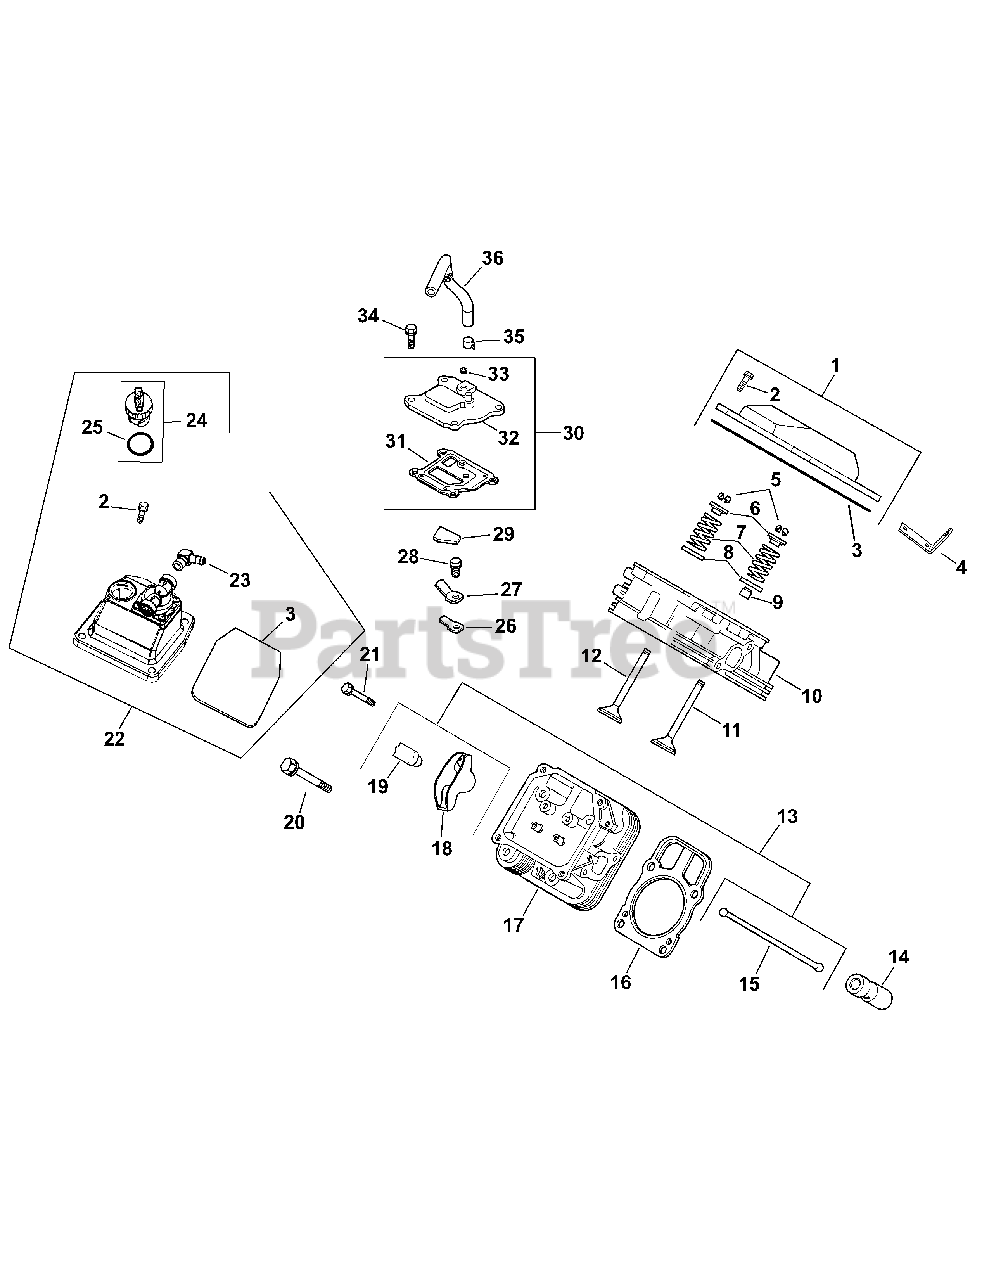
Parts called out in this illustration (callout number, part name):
1	Kit, Valve Cover-Plain Inc. 2, 3)
2	Screw, Flg M6x1.0x30
3	O-Ring, Valve Cover
4	Strap, Lifting
5	Kit, Retainer
6	Cap, Valve Spring
7	Spring, Valve
8	Retainer, Spring
9	Seal, Valve Stem
10	Kit, #1 Cylinder Head Assy
11	Valve, Intake (Std)
11	Valve, Intake (.25)
12	Valve, Exhaust (Std)
12	Valve, Exhaust (.25)
13	Kit, Valve Train (Includes 15,18,19)
14	Hydraulic Valve Lifter
16	Kit, Cylinder Head Gasket
17	Kit, #2 Cylinder Head Assy
19	Pivot, Rocker Arm
20	Screw, Flg M10x1.5x90
21	Screw, Flg M6x1.0x34
22	Kit, Valve Cover-Fuel Pump
23	Kit, 90 Deg. Fitting
24	Cap Assy, Oil Fil (Yellow) (Inc. 25)
26	Reed Retainer
27	Reed, Breather
28	Screw, Flg Thd Frm M5x0.8x10
29	Filter, Breather
30	Kit, Breather Ass’y (Inc. 31-33)
31	Gasket, Breather
32	Kit, Breather Ass’y
33	Plug, Pipe CTSK 1/8"
34	Screw, Flg Thd Frm M6x1.0x20
35	Hose Clamp, 1/2"
36	Hose, Breather
